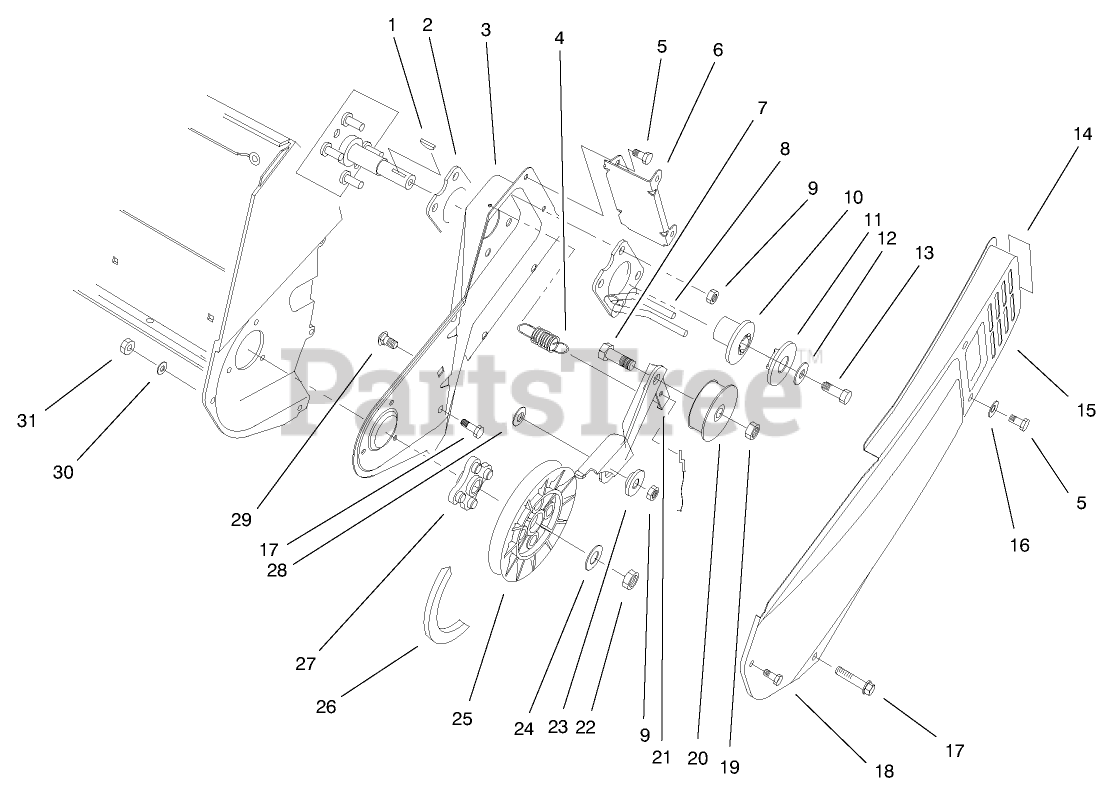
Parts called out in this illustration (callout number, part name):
1	KEY-WOODRUFF
2	PLATE-ENGINE
3	SIDEPLATE-LH
4	SPRING-BRAKE
5	SCREW-HWH
6	BRACKET-COVER, BELT
7	SCREW-HH
8	GUIDE-BELT
9	NUT-LOCK, NI
10	HUB-HALF SHEAVE
11	CAP-HALF SHEAVE
12	WASHER-FLAT
13	SCREW-HH
14	DECAL-HOT
15	COVER-BELT
16	WASHER-FLAT
17	SCREW-PLASTIC
20	PULLEY-IDLER
21	ARM-BRAKE
22	NUT-LOCK, NI
23	BUSHING-IDLER
24	WASHER-FLAT
25	PULLEY-DRIVEN
26	V BELT
28	WASHER
29	SCREW-CARR
30	WASHER-FLAT
31	NUT-LOCK, NI
